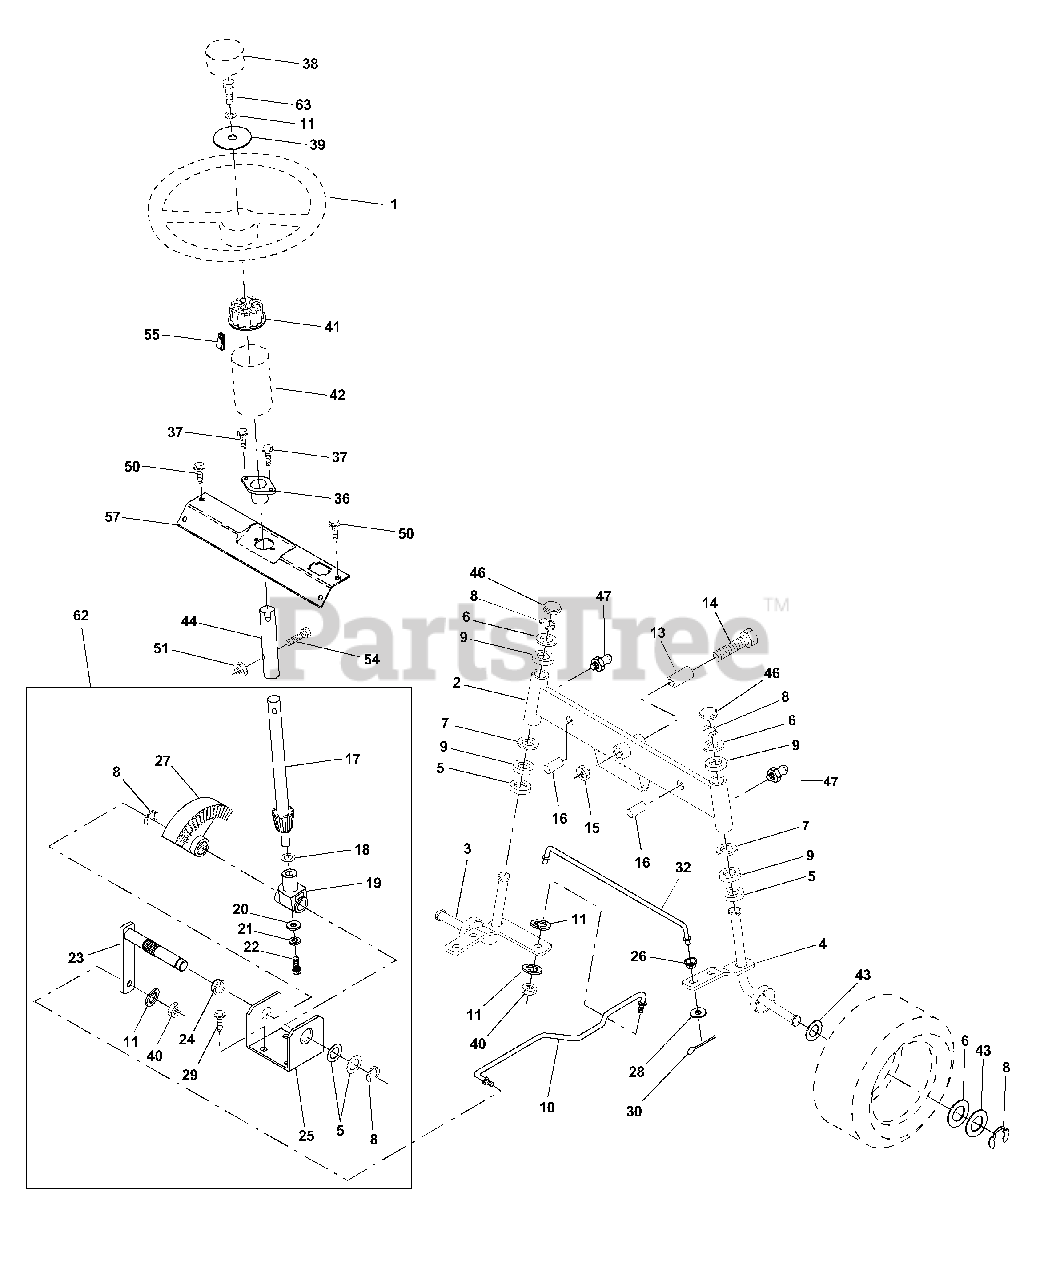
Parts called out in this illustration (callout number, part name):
1	Wheel Steering Auto Grey
2	Axle Asm Fr LT W/gzks 38/42
3	Spindle Asm LH
4	Spindle Asm RH
5	Bearing Race Thrust Harden
6	Washer 25/32 X 1-5/8 X 16 Ga
7	Washer 27/32 X 1-1/4 X 16 Ga
8	Ring Klip #t5304-75
9	Bearing Col Strg Blk
10	Link Drag Sol Ball Jt 20 064
11	Washer Lock Hvy Hlcl Spr 3/8
12	Nut Fin Hex 3/8-24 Unf
13	Spacer Bearing Axle Front
14	Bolt Hex 5/8-11 Unc X 3-1/2
15	Nut Lock Flange 5/8-11 Unc
16	Pin Axle 5/8 X 1 55/1 54 Lg
17	Shaft Asm Strg Private Label
18	Washer Thrust 515x 750x 033
19	Support Shaft
20	Washer Shim 1/4 X 5/8 X 062
21	Washer Lock Hvy Helical 1/4
22	Screw Cap Sckt Hd Phos & Oil
23	Shaft Asm Pittman
24	Nyliner Snap In
25	Bracket Steering
26	Bushing Link Drag Blk LR
27	Gear Sector
28	Washer 13/32 X 7/8 X 16 Ga
29	Screw Thdrol 3/8-16x3/4 Ty-tt
30	Pin Cotter 1/8 X 3/4 Cad
32	Rod Tie Wire Form 19 75 Mech
36	Bushing Strg
37	Screw Tt #10-32 5 3/8 Flange
38	Insert Cap Strg Wh Au
39	Washer 13/32 X 2-3/8 X 8 Ga
40	Lock nut
41	Adaptor Wheel Strg 640/ 635id
42	Boot Steering Shaft
43	Washer 25/32 X 1 1/4 X 16 Ga
44	Extension Shaft Steering
46	Cap Spindle Fr Top Blk
47	Fitting Grease
50	Screw Hex Wsh Thdrol 1/4-20 x 3/4
51	Nut Lock Hex w/Ins 5/16-18
54	Bolt Fin Hex 5/16-18 Unc x 1-1/4
55	Clip Tinnerman
57	Support Shaft Steering
62	Kit, Steering Assembly
63	Bolt Fin Hex 3/8-16 Unc x 1 Gr. 5
